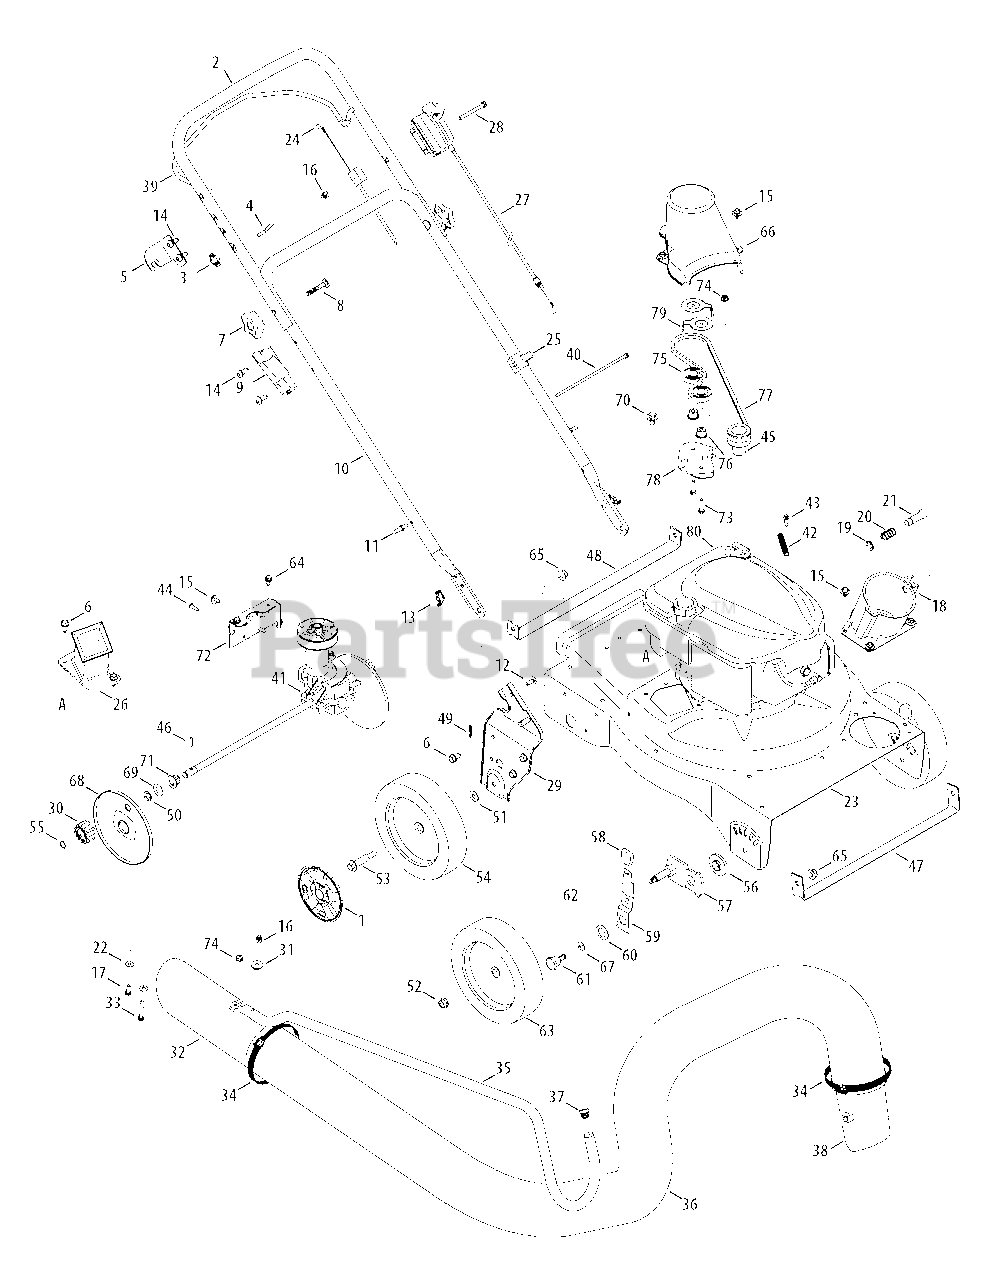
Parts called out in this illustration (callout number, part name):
1	Hub Cap
2	Upper Handle
4	Eye Bolt
5	Upper Handle Bracket
6	Hex Cap Screw 5/16-12 x.750
7	Handle Knob 5/16-18
8	Carriage Bolt
9	Nozzle Handle Clip
10	Lower Handle
11	Studs
12	Carriage Screw 1/4-20 x.75
13	Wing Nut 1/4-20
14	TT Screw, 5/16-18 x .750
15	Screw, 1/4-20 x .500
16	Cap Lock Nut, 1/4-20
17	Hex Cap Screw 1/4-20 x.620
18	Hose Base Adapter Assembly
19	E Ring.500 Dia
20	Compression Spring
21	Clevis Pin
22	Flat Washer.271 ID x.630 OD
23	Upper Flail Housing
24	Drive Control Cable
25	Cable Guide
26	Chipper Chute Assembly
27	Speed Control Cable
28	Hex Screw, 1/4-20 x 2.50
29	Handle Bracket Ass’y RH
30	Spur Gear - RH
31	Spacer
32	Hose Nozzle
33	Hex Cap Screw 1/4-20 x 2.625
34	Adjustment Clamp
36	Vacuum Hose
37	Handle Plug
38	Hose Adapter
39	Drive Control
40	Cable Tie
41	Transmission Assembly
42	Extension Spring,.375 x 2.95
43	Shoulder Screw, #12-24 x .30 x .46
44	Screw, #12-16 x .750
45	Impeller Hub
46	Dowel Pin
47	Front Wheel Support Brace
48	Rear Wheel Support Brace
49	Cotter Pin
50	E-Ring
51	Flat Washer, .406 x .875 x .105
52	Nut, Flglk., 3/8-16
53	Shoulder Screw, .496 x 1.605
54	Rear Wheel
55	Snap Ring
56	Height Adjustment Bearing
57	Pivot Arm Assembly
58	Height Adjustment Knob
59	Spring Lever
60	Bell Washer.760 ID x.25 OD
61	Shoulder Screw,.750 x.500
62	Hgt Lever Assy (Incl. Ref.# 58-59)
63	Front Wheel
64	Screw, 1/4-20 x .625
65	Flange Lock Nut, 3/8-16
66	Belt Cover
67	Thrust Washer.375 ID x.70 OD
68	Wheel Cover
69	Flat Washer,.508ID x1.00OD x.020
70	Shoulder Screw,.560 x.165
71	Drive Axle Bushing
72	Transmission Mounting Bracket
73	Screw, 1/4-20 x 1.00
74	Flange Lock Nut, 1/4-20
75	Ball Bearing
76	Flange Spacer,.260 x.659 x.517
77	Belt, 3/8 x 32.5
78	Idler Bracket
79	Belt Keeper
